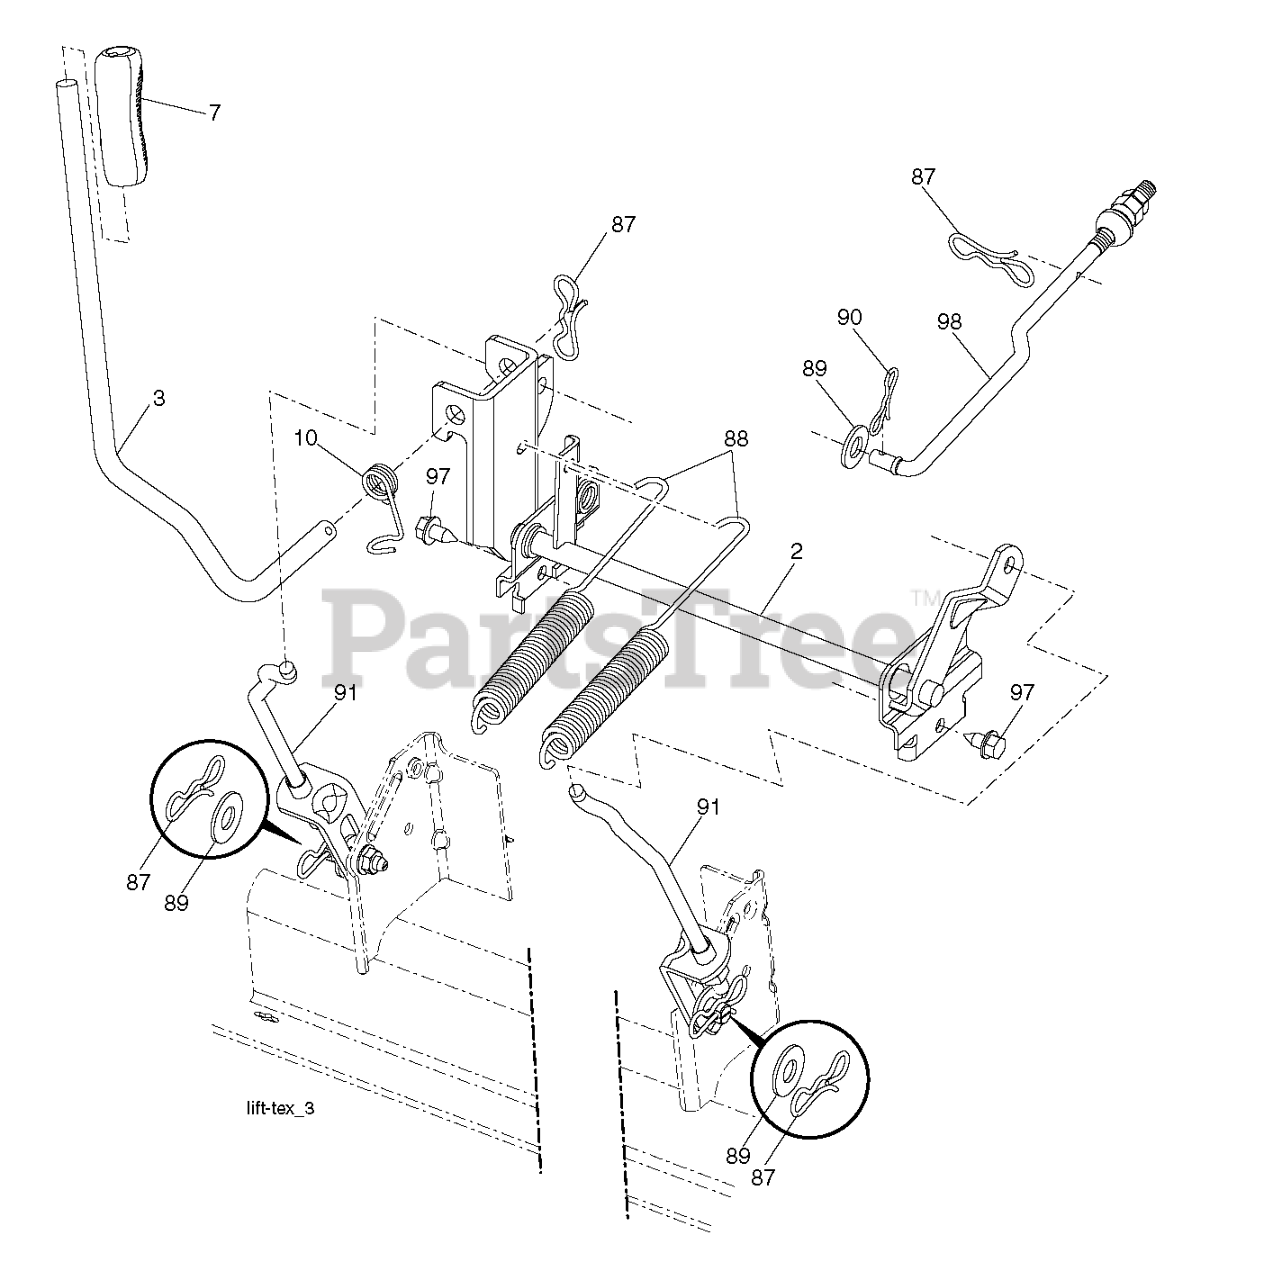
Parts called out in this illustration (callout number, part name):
2	SHAFT.ASM.CROSS.LIFT
3	LEVER.LIFT.HANDLE.LT
7	GRIP.HANDLE.LIFT.PVC.BLACK
10	SPRING.TORSION.LIFT.HANDLE
87	PIN.COTTER.7/16.BOW TI.
88	SPRING.LIFT.ASSIST
89	WASHER.CLEAR.ZINC
90	PIN.COTTER.5/16.BOW TI
91	LINK.ASM.LIFT.REAR
97	SCREW, 3/8-16X3/4
98	LINK.ASM.SUSP.FRONT.MWR.10.5
